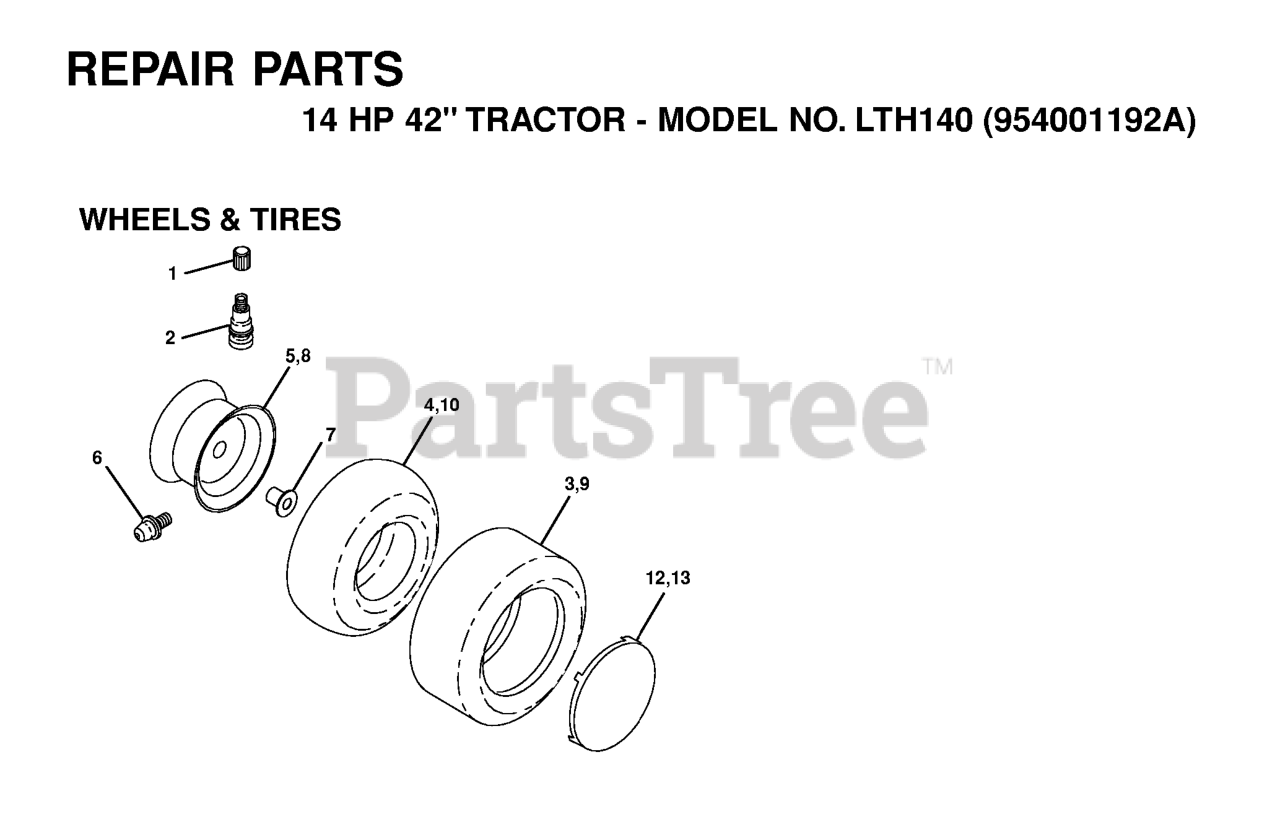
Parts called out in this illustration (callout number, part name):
2	VALVE STEM LT
3	TIRE HEAVY DUTY
4	TUBE.5.3/4.5/6
5	RIM FRONT 6"
6	FITTING LT
7	BEARING T
8	RIM.ASM.8X7.REAR.WHITE
9	TIRE.TS.20X10-8
10	TUBE
12	COVER.FRONT.WHEEL
13	CAP,HUB REAR
